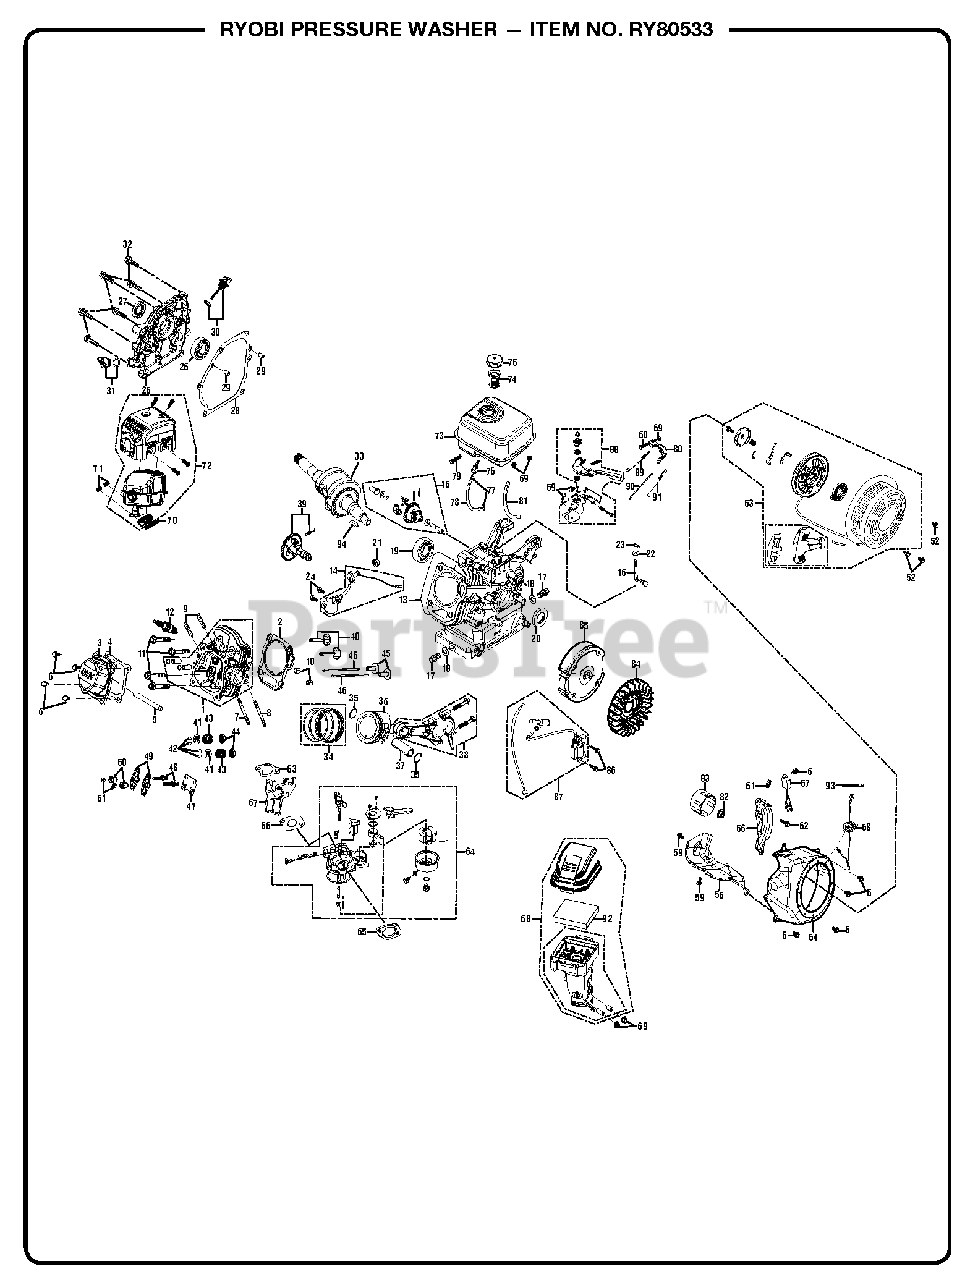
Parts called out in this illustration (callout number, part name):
1	Cylinder Head Sub-assembly
2	Cylinder Head Gasket
3	Cylinder Head Cover Sub-assembly
4	Cylinder Head Cover Gasket
11	Cylinder Head Bolt
13	Crankcase Sub-assembly
14	Engine Oil Sensor
15	Governor Gear Assembly
22	Governor Gear Washer
25	Crankcase Cover
28	Crankcase Gasket
30	Oil Dipstick Sub-assembly
31	Engine Oil Plug Sub-assembly
33	Crankshaft Assembly
34	Piston Ring Assembly
35	Piston Pin Clip
36	Piston Assembly
39	Camshaft Assembly
41	Valve Spring Seat
42	Valve Lock Clip
47	Lifter Stopper Plate Sub-assembly
48	Valve Adjusting Bolt
50	Valve Adjusting Nut
53	Recoil Starter Assembly
55	Cylinder Body Shroud
58	Stop Engine Switch Assembly
60	Governor Support Bolt
63	Insulator Carburetor Gasket
64	Carburetor Assembly
65	Air Cleaner Gasket
66	Carburetor Gasket
67	Carburetor Insulator Plate
72	Muffler Assembly
75	Fuel Tank Cover
76	Fuel Tank Oil Outlet Assembly
80	Governor Support Sub-assembly
85	Flywheel Sub-assembly
87	Ignition Coil
88	Throttle Control Assembly
89	Governor Spring
91	Throttle Valve Returning Spring
